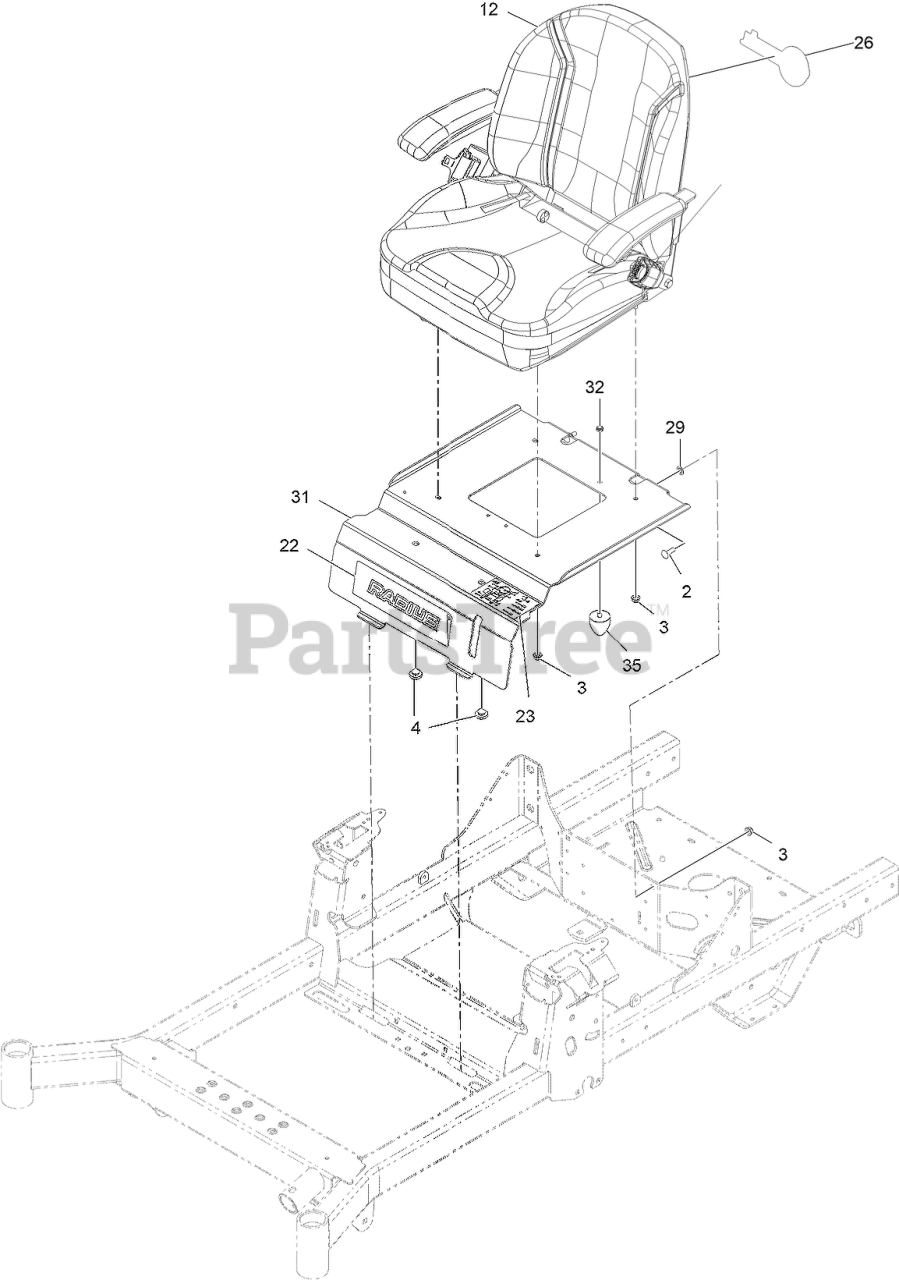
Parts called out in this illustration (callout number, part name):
2	SCREW-CARR
3	NUT-HF, NI
4	BUMPER-SEAT
12	ASM-SEAT EXMARK
22	DECAL-RADIUS LOGO
23	DECAL-AID, SERVICE
26	DECAL, EXMARK LOGO
29	Washer-Retaining
31	PLATE-FIXED SEAT
32	NUT-LOCK, NI
35	BUMPER-RUBBER
